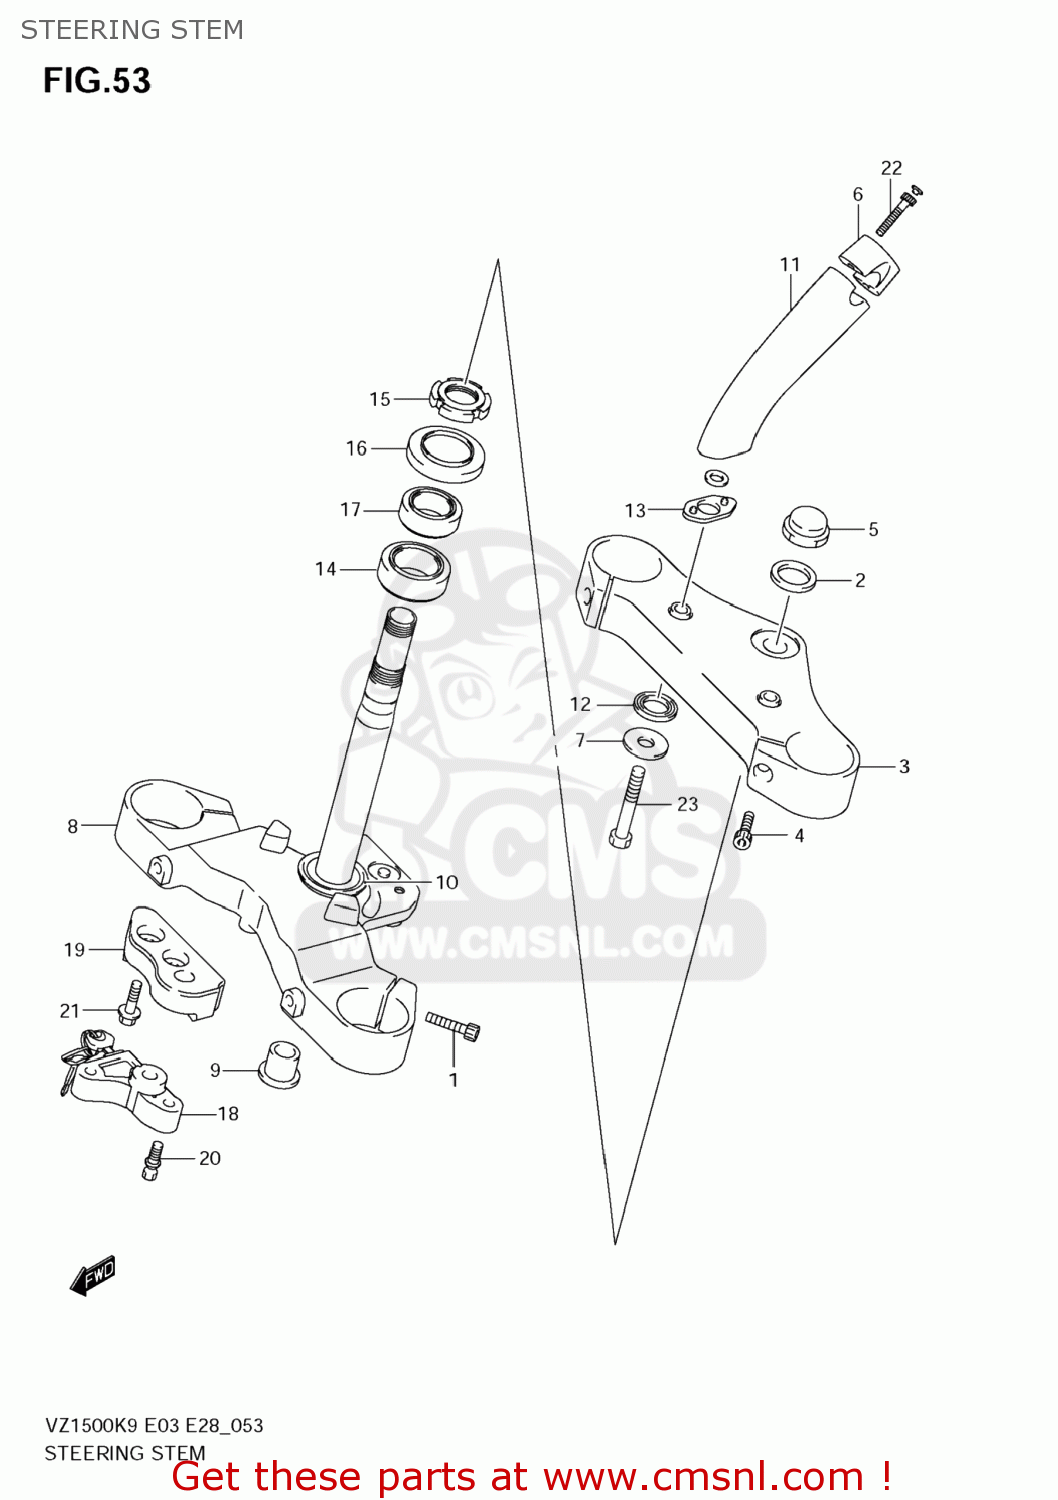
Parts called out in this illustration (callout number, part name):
1	BOLT,BRACKET LOW
2	WASHER(22.5X35.9X1.6)
3	BRACKET,UPR
4	BOLT
5	NUT,CAP
6	HOLDER,HANDLE
7	WASHER
8	BRACKET,UNDER
9	CAP
10	SEAL,STEERING LWR
11	HOLDER,HANDLE
12	RUBBER,HANDLE HOLDER
13	RUBBER,HANDLE HOLDER
14	BEARING(30X55X17)
15	NUT,STEERING STEM
16	DUST SEAL,STEERING UPR
17	BEARING(25X47X15)
18	LOCK SET,STEERING
19	BRACKET,STEERING LOCK
20	SCREW,STEERING LOCK
21	BOLT(8X30)
22	BOLT,BRACKET LOW
23	BOLT
